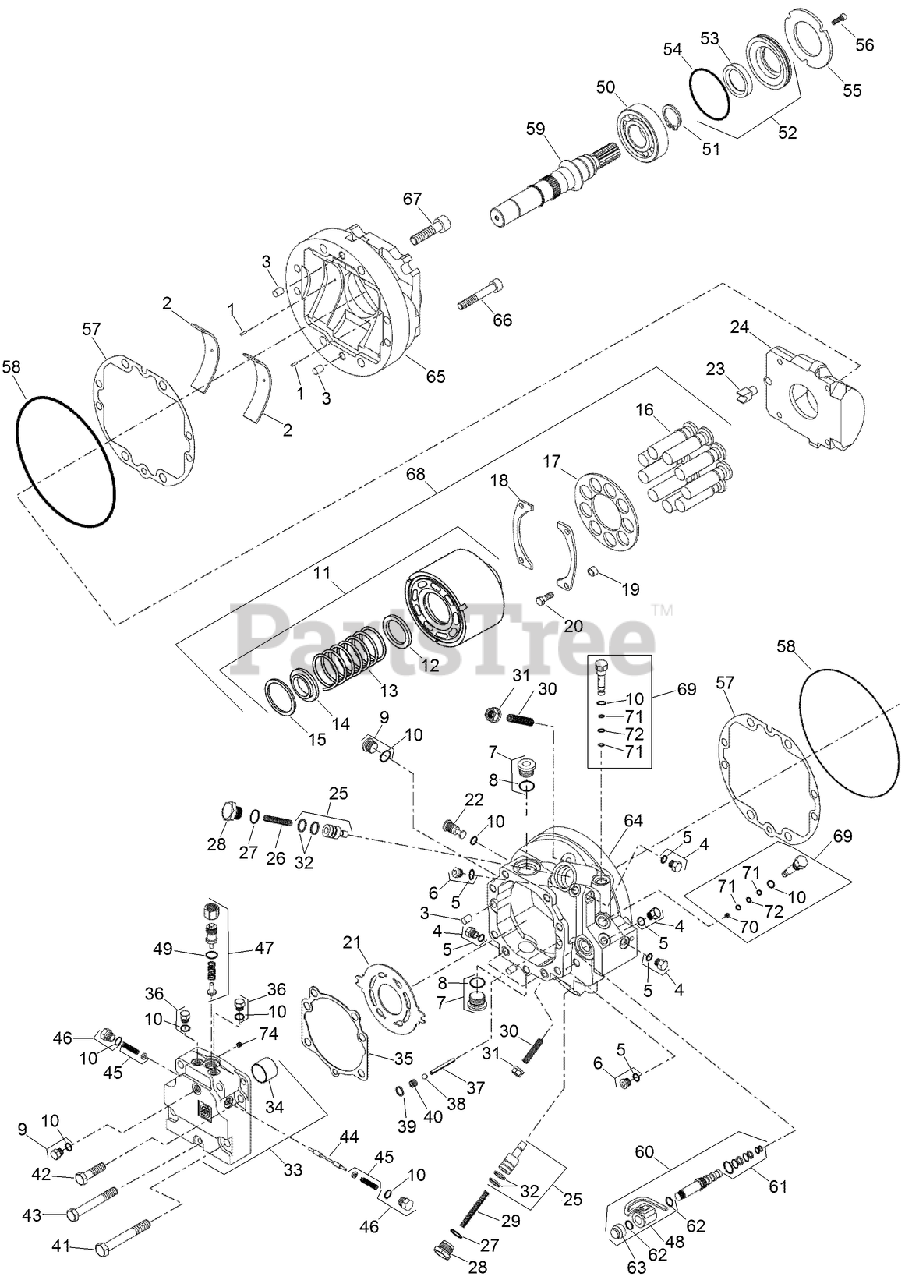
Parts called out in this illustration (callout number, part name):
1	PIN - Grooved
2	BEARING - Cradle
11	ASSEMBLY - Cylinder Block
12	SEAT - Spring
13	SPRING - Cylinder Block
14	RETAINER - Spring
15	RING - Retainer
16	PISTON - Welded
17	GUIDE - Slipper
18	BEARING - Slipper Guide
21	PLATE - Motor Valve
22	PIN - Hold Down
23	ARM - Hold Down
24	SWASHPLATE - Variable
25	ASSEMBLY - Servo Piston
27	O-RING
30	SCREW - Set
31	NUT - Seal
32	SEAL - Piston Ring
33	CAP - End, Twin Ports
34	BEARING - Journal
35	GASKET - End Cap
37	PIN - Slotted
39	RING - Crush
40	PLUG - Orificed Pipe
44	VALVE - Loop Flushing
45	ASSEMBLY - Spring Guide
46	ASSEMBLY - Plug
47	KIT - Charge Relief Cartridge Valve
48	KIT - Coil, 12V Packard Connector
50	BEARING - Roller
51	RING - Retaining
52	ASSEMBLY - Shaft Seal
53	SEAL - Lip
55	PLATE - Retainer
57	GASKET - Front Cover
59	SHAFT - 14 Tooth Spline
60	KIT - Solenoid Valve, 12V Packard Connector
61	KIT - Seal, Solenoid Valve
64	ASSEMBLY - Variable Motor Housing
65	COVER - Front
68	KIT - Cylinder Block
69	PLUG - Orifice
70	SCREEN - Filter
71	RING - Back Up
74	SCREW - Set
